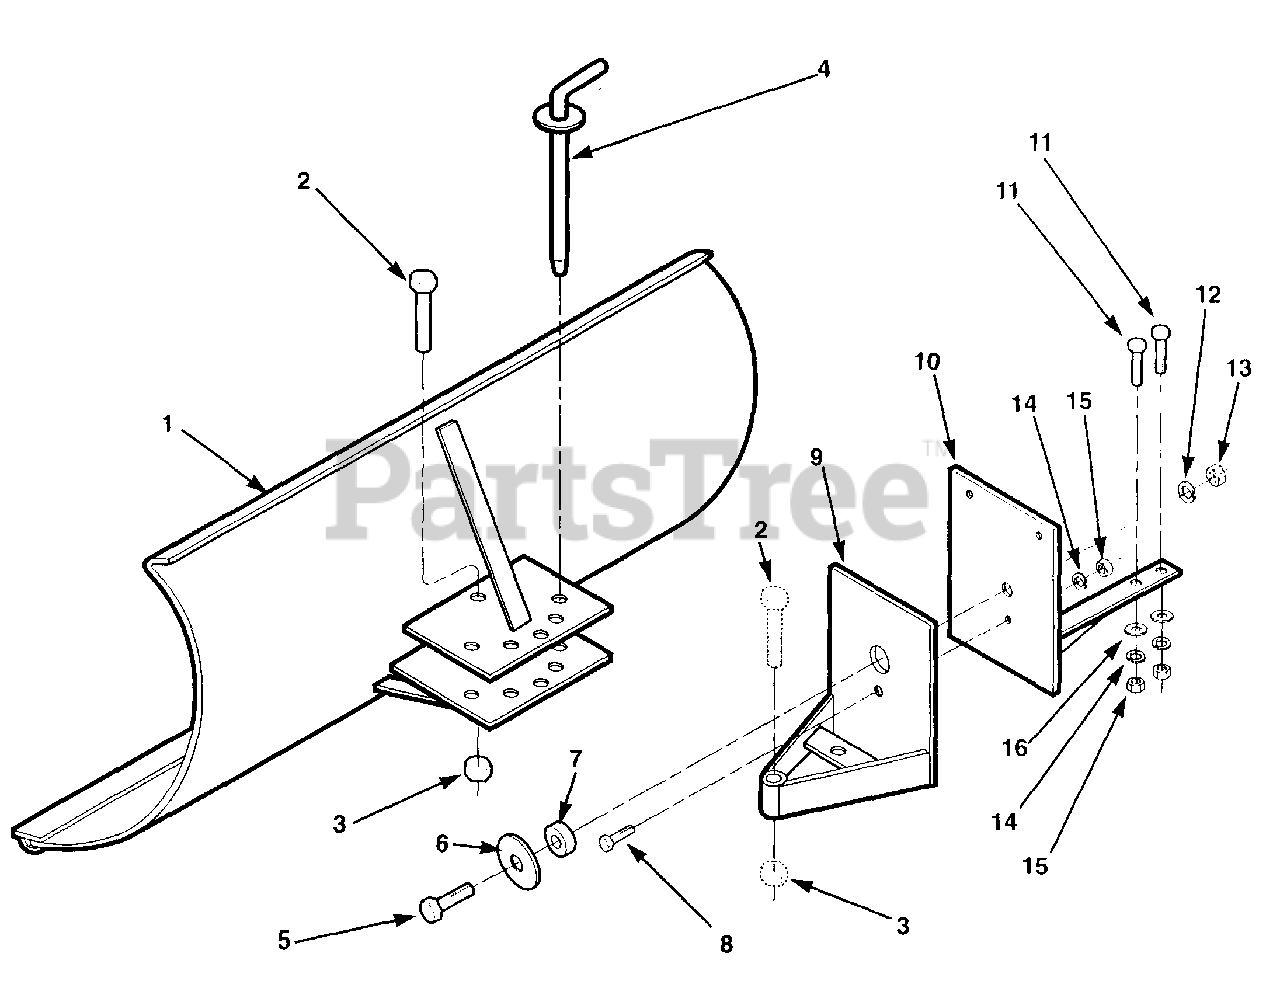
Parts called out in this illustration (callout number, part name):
1	Blade - dozer/snow blade
2	Bolt - hex hd., 1/2-13 x 3"
3	Locknut - hex, 1/2"-13
4	Pin - index, blade angle adjust
5	Bolt - hex hd,, 1/2-13 x 1-1/2"
6	Washer - plain, 1/2"
7	Bushing
8	Bolt - hex hd., 5/16-18 x 1-1/4"
9	Bracket - swivel ("A" frame)
10	Bracket - dozer mounting
11	Bolt - hex hd., 5/16-18 x 1-3/4"
12	Lockwasher - spring lock, 1/2"
13	Nut - hex, 1/2"-13
14	Lockwasher - spring lock 5/16"
15	Nut - hex, 5/16" x 18
16	Washer - plain, 5/16", S.A.E.
